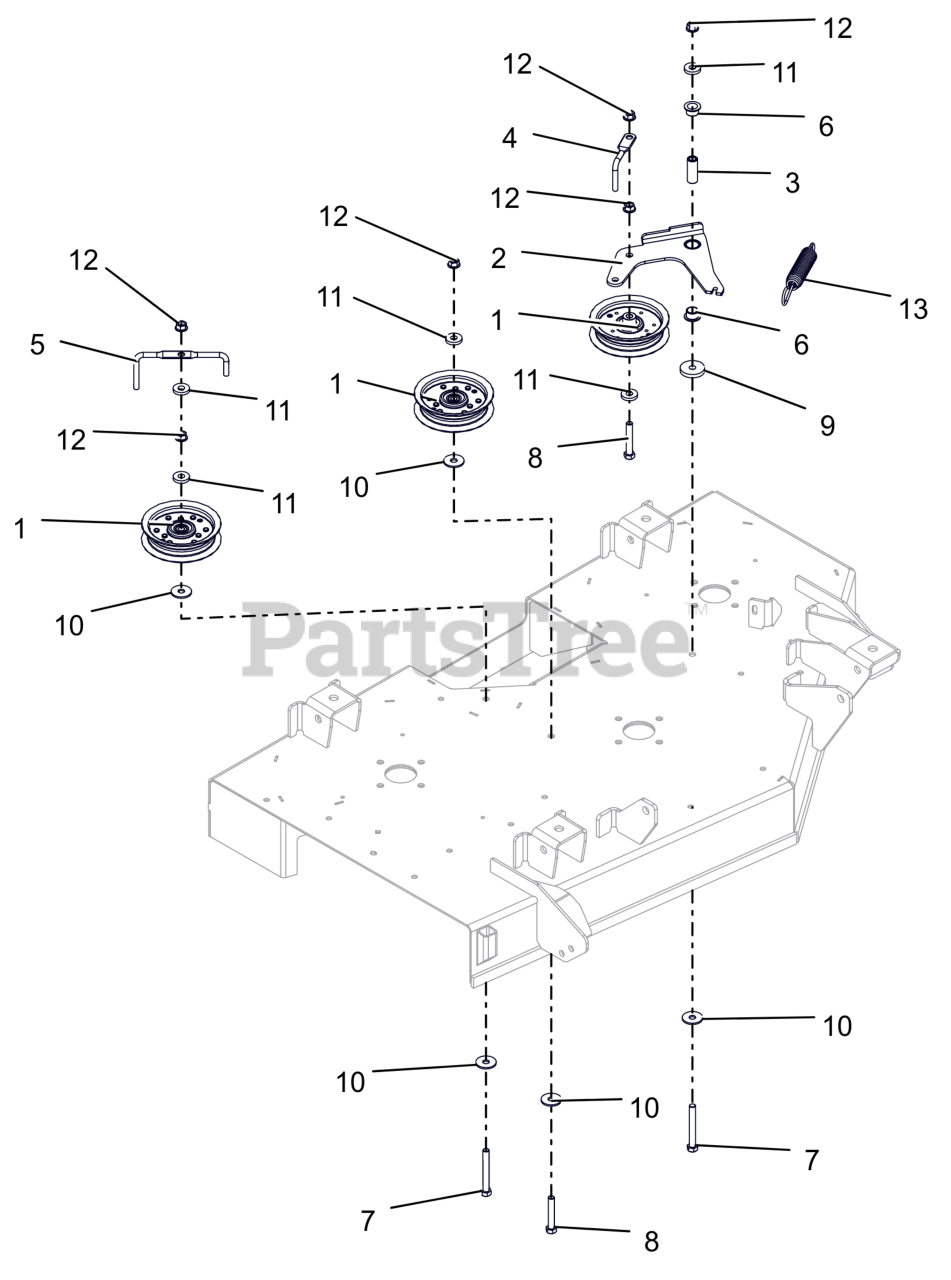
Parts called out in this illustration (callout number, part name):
1	ASM, IDLER 4"
2	WLDMT, IDLER ARM-42"
3	SPACER, .375IDX.625ODX1.66 PM
4	WIREFORM, BELT FINGER
5	WIREFORM, BELT FINGER
6	BSHG-FLG, .625X.750X.500X1.00
7	BLT, HEX .38-16X3.00F G5 ZCC
8	BLT,HEX .38-16X2.25 G5 ZCC
9	WSHR, FLT .406X1.50X.245 ZCC
10	WSHR FL STL .406X1.25X.10ZC120
11	WSHR, FLT .406X1.00X.188 ZCC
12	NUT-LK-CTR-FLG .375-16 GF ZCC
13	SG-TENS .135X.98X6.0 WLD 62
